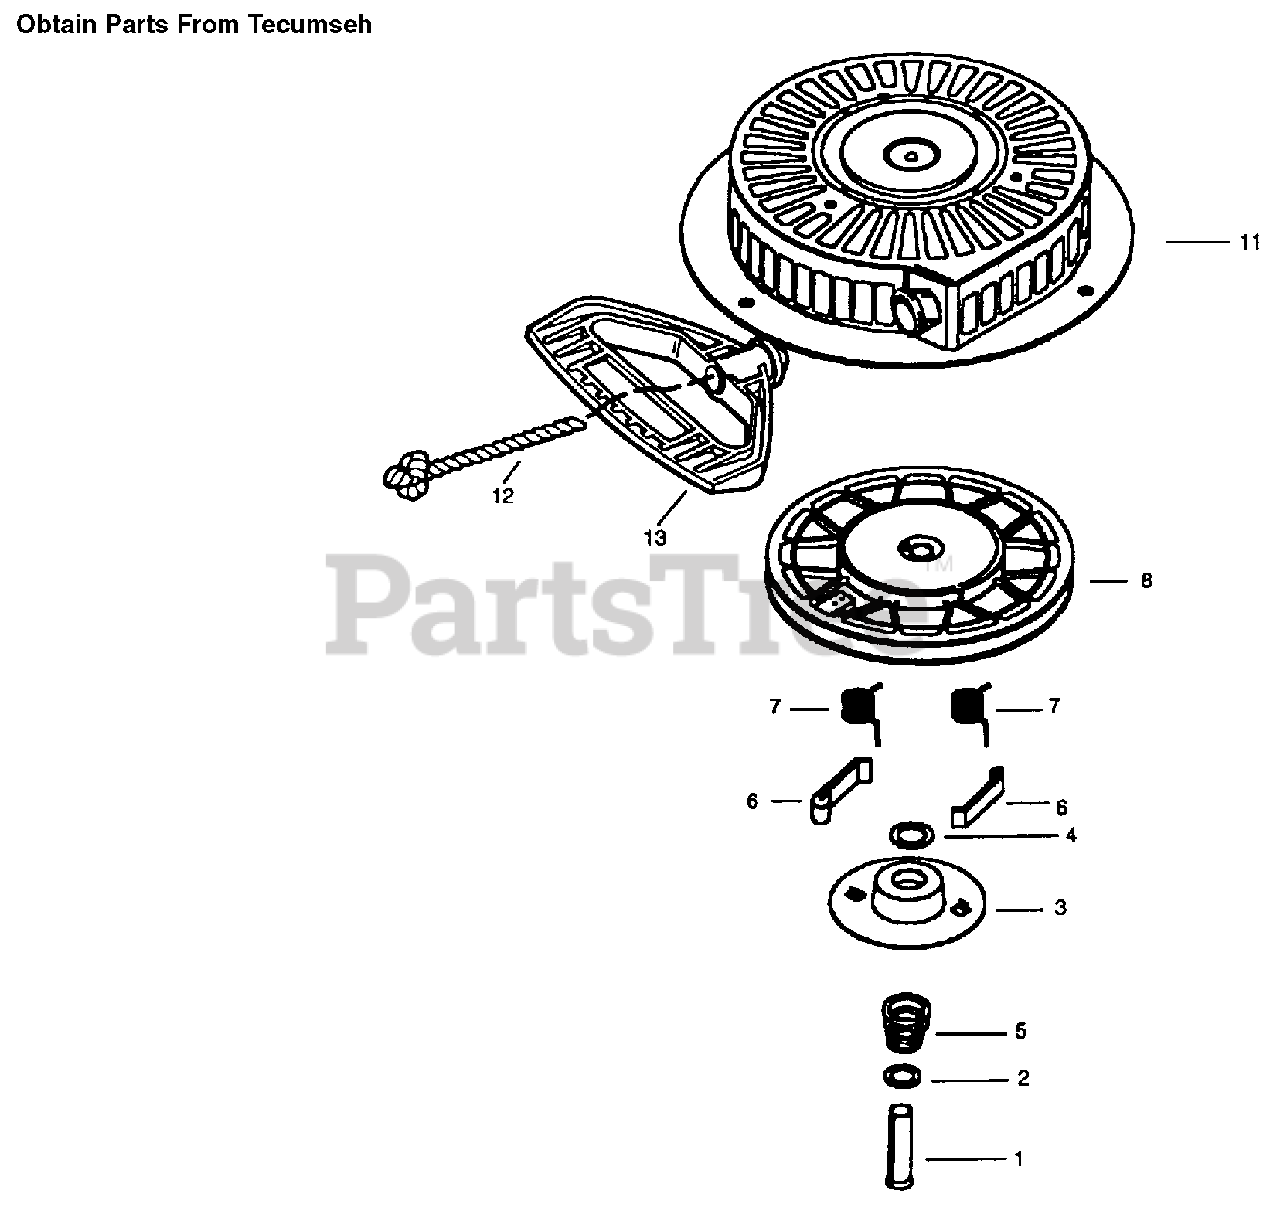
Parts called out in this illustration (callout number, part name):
1	Pin-Spring (Incl. Ref. #4)
3	Retainer
5	Spring-Brake
6	Dog-Starter
7	Spring-Dog
8	Pulley & Rewind Spring Assembly
11	Starter Housing Asm
12	Rope-Starter
13	Handle-Mitten Grip
